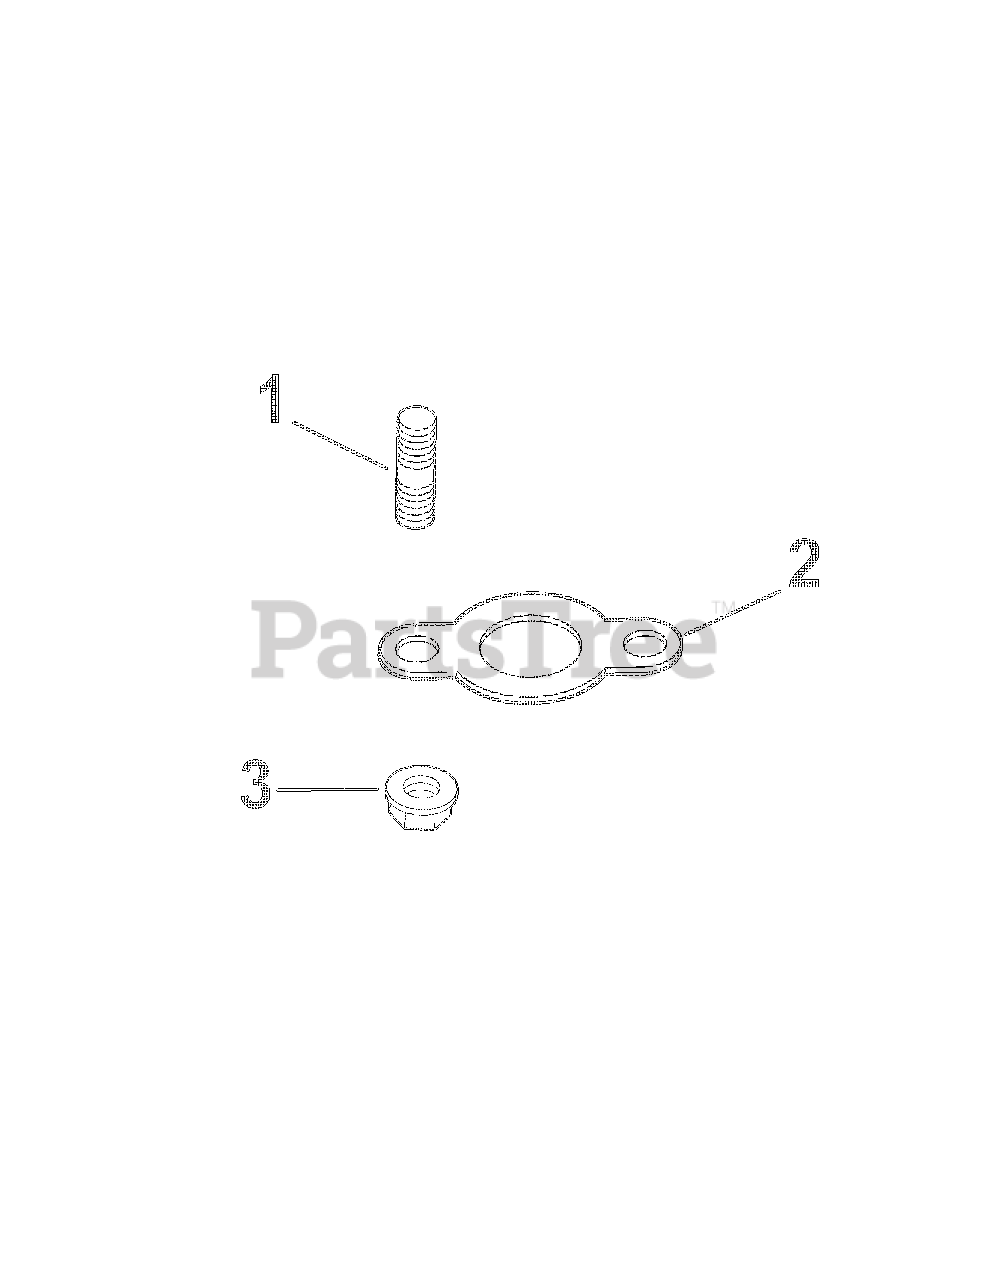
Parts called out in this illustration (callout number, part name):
1	Stud M8x1.25x33 (4)
2	Gasket, exhaust manifold (2)
3	Nut, hex. flange M8x1.25 (5)
